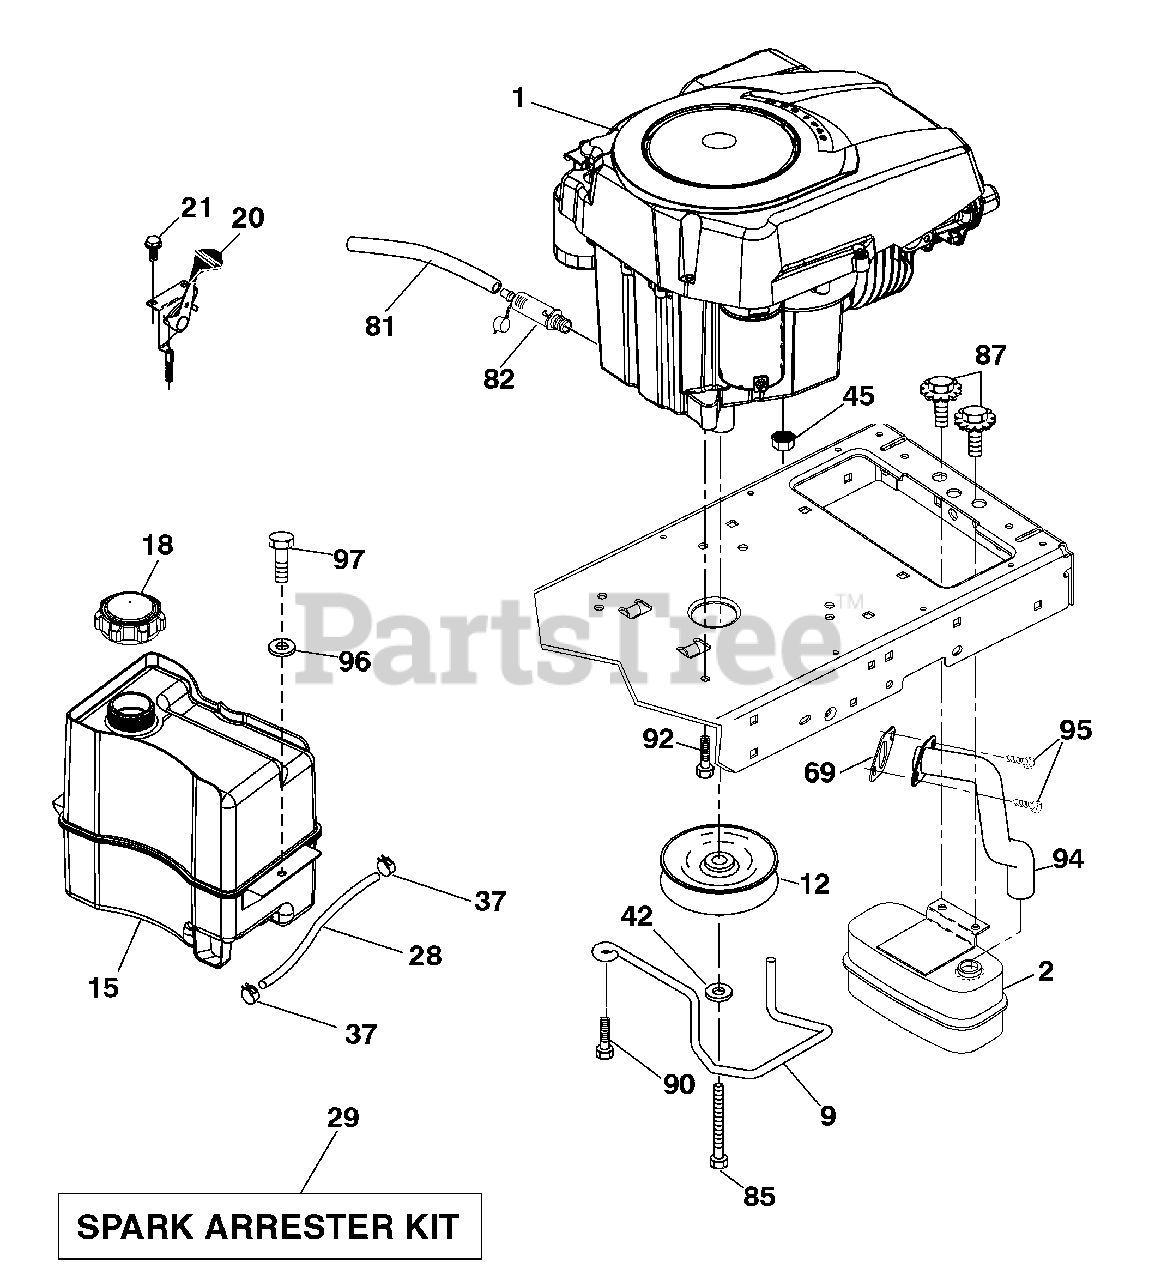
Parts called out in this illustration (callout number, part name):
9	Keeper Belt Engine
12	Pulley Engine
15	Tank Fuel
18	Cap Asm
20	Control Throttle
21	Screw 10 x 3/4 Single Lead Hex
28	Fuel Line
29	Spark Arrester Kit
37	Clamp Hose
42	Washer Lock 7/16
45	Nut Keps Hex 1/4-20 unc
81	Tube Drain Oil Easy
82	Plug Drain Oil
85	Bolt Hex 7/16-20 x 4 x Gr. 5-1.5 Thr
87	Bolt 5/16-18 UNC x 3/4 w/Sems
90	Screw 3/8-16 x 1
92	Screw 3/8-16 x 1
94	Tube Exhaust
95	Screw Socket Hd. 5/16-18 x .75
96	Washer 9/32 x 7/8 x 16 Ga.
97	Screw 1/4-20 x 3/4
